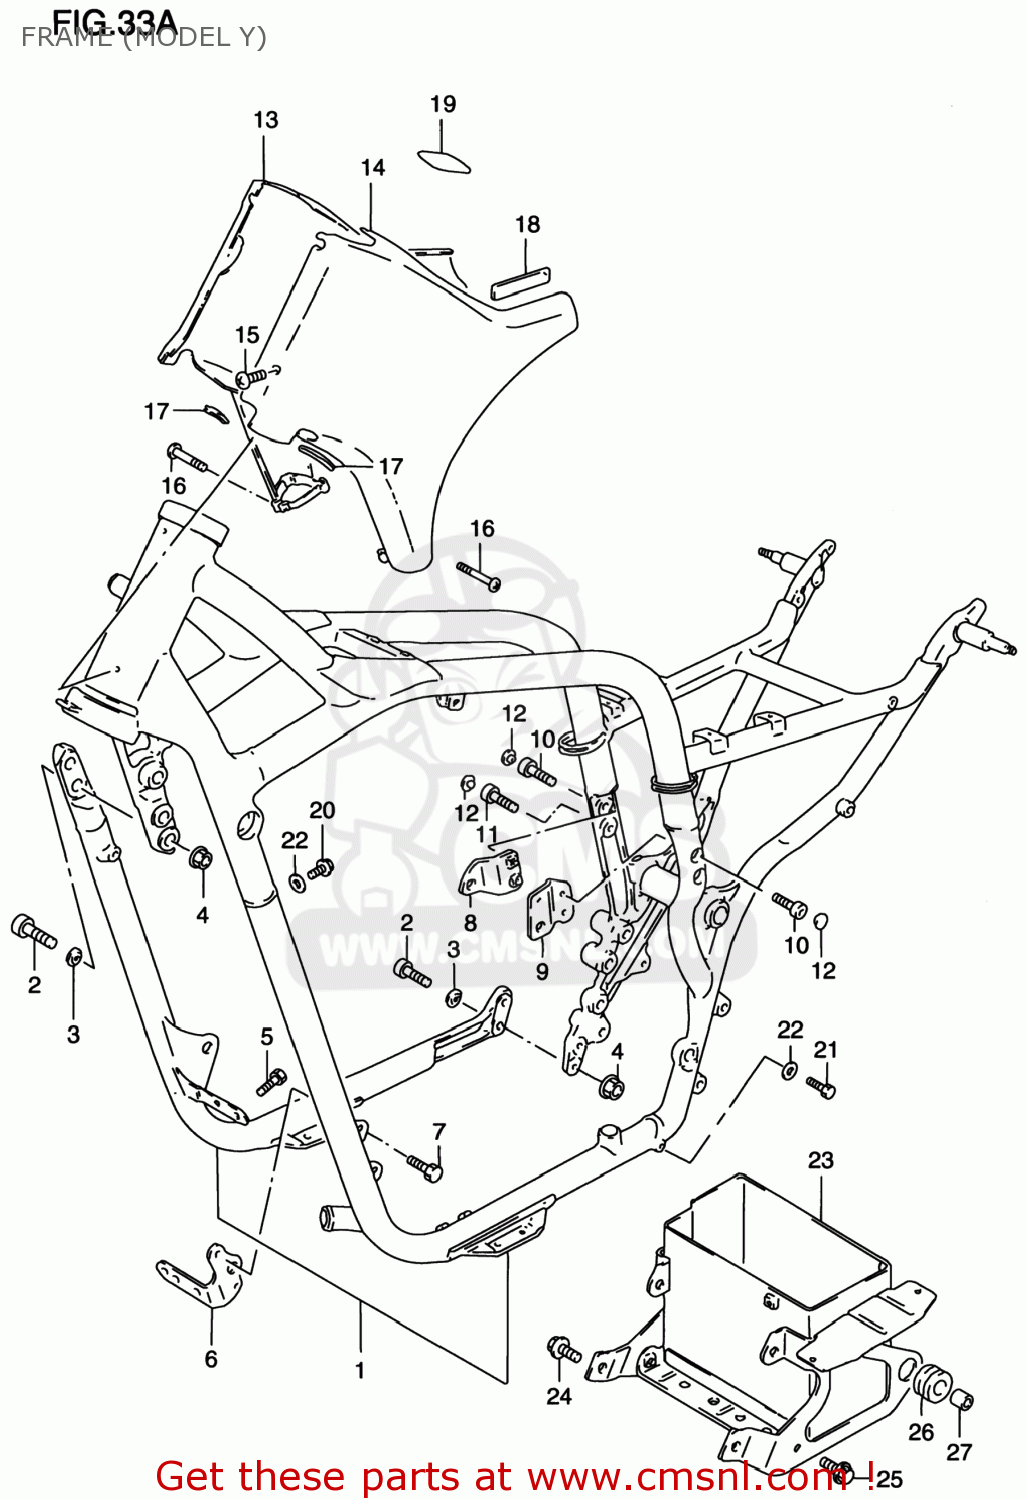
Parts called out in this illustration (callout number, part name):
1	FRAME SET(RED)
2	BOLT(10X33)
3	WASHER
4	NUT
5	BOLT, FRONT
6	PLATE,ENGINE MOUNT NO.1,L
7	BOLT, UPPER
8	PLATE,ENGINE MOUNT NO.3,R
9	PLATE,ENGINE MOUNT NO.3,L
10	BOLT(8X30)
11	BOLT
12	CAP(OD:14.5)
13	COVER,FRAME HEAD,RIGHT
14	COVER,FRAME HEAD,LEFT
15	SCREW 6X10
16	SCREW
17	MOLDING,FUEL TANK
18	PROTECTOR(80X80X2)
19	TAPE,FRAME HEAD COVER
20	UNION
21	BOLT
22	GASKET(6.2X11X1).2 (NAS)
23	HOLDER,BATTERY
24	BOLT
25	BOLT
26	CUSHION
27	BUSH
